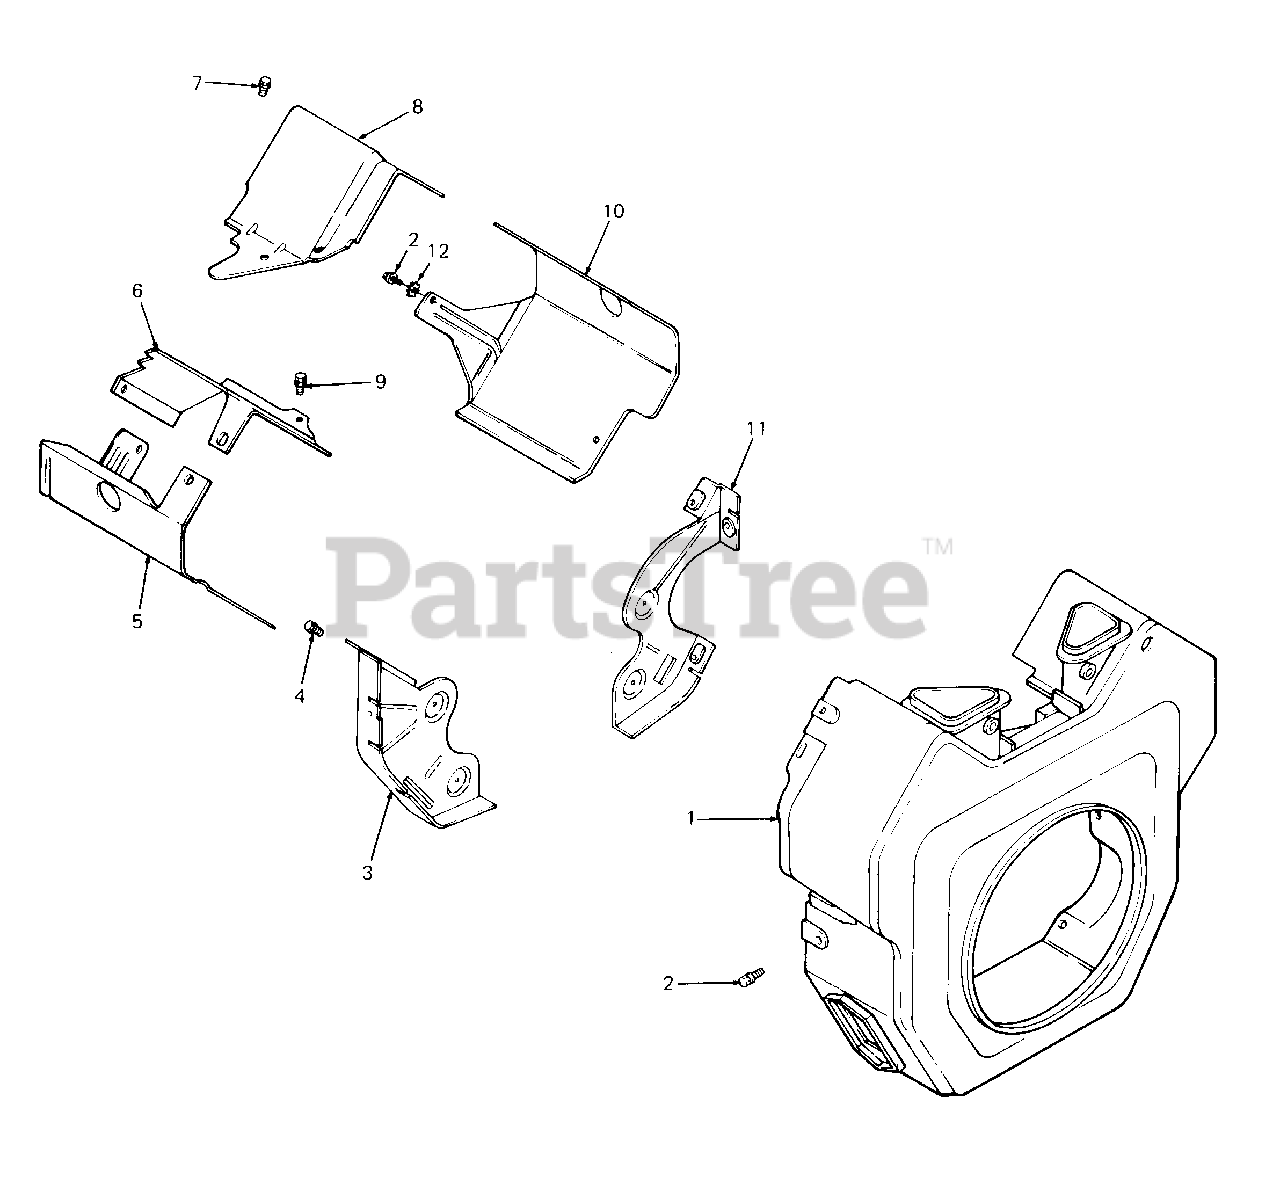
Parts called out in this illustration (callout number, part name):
1	Housing, Blower
2	Screw, M5 X 0.8 X 16
3	Plate, Backing #2
4	Screw, M6 X 1.0 X 16
5	Baffle, Cylinder Barrel #2
6	Baffle, Valley, #2
7	Screw, M5 X 0.8 X 10
8	Baffle, Valley #1
9	Screw, M6 X 1.0 X 16
10	Baffle, Cylinder Barrel #1
11	Plate, Backing #1
12	Washer, I.T./E.T., 1/4
